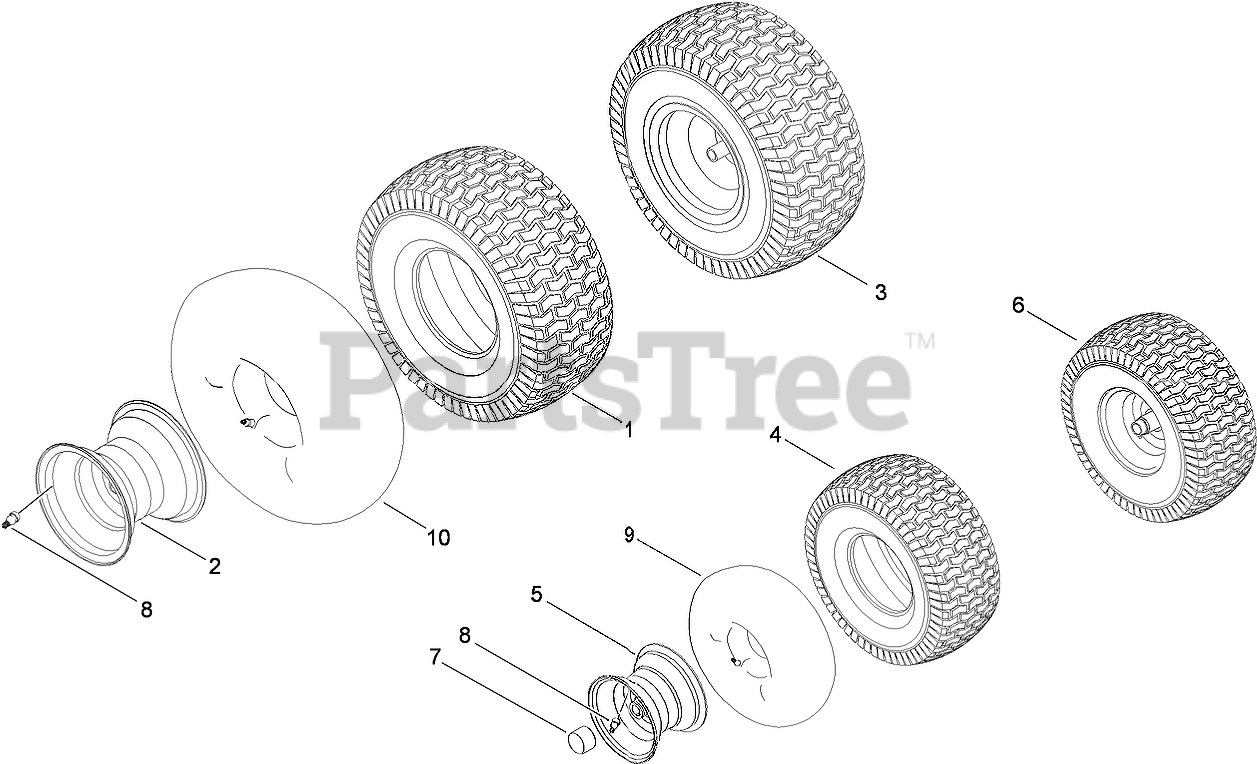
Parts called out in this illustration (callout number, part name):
1	TIRE-MULTI TRAC
2	RIM-WHEEL, REAR
3	Rear WHEEL ASM
4	TIRE-FRONT
5	Rim-Wheel, Front
6	Front WHEEL ASM
7	CAP-HUB
8	VALVE-AIR, TUBELESS
9	TUBE-INNER
10	TUBE-INNER
